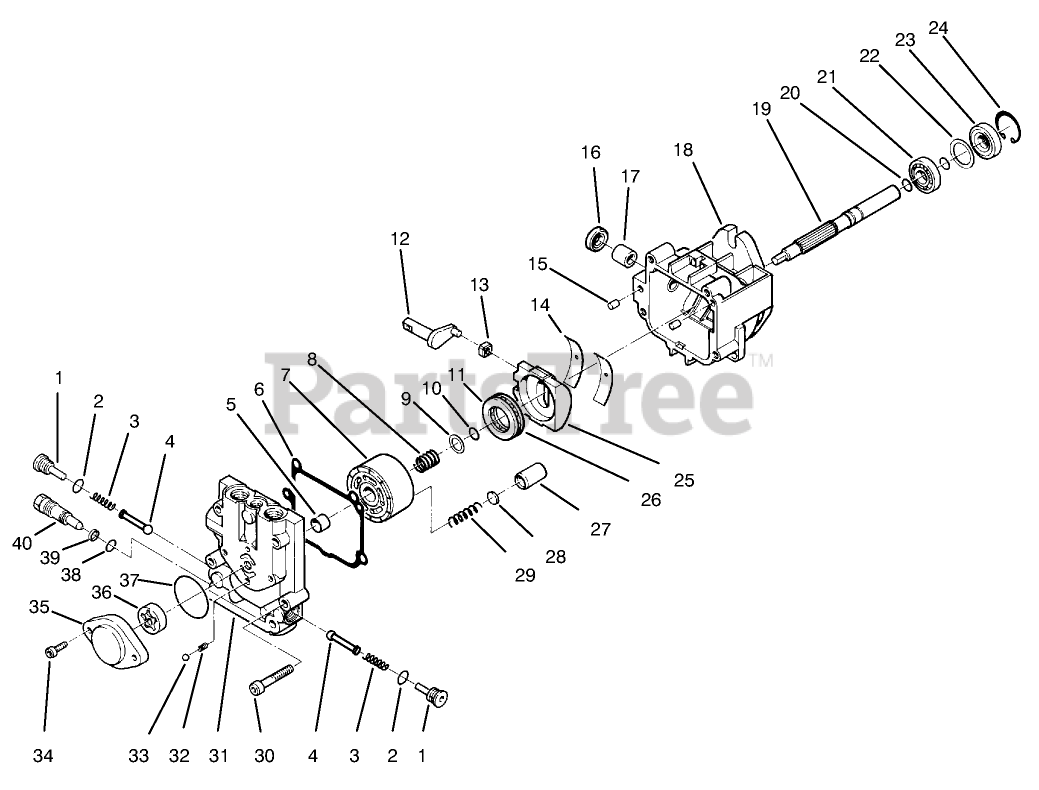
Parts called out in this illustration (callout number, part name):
1	Check Valve Kit (Incl. Ref. #2-4)
2	Seal-O-Ring
4	Poppet
5	Journal-Bearing
6	Gasket-End Cap
9	Washer
11	Plate-Thrust
12	Arm-Trunnion
13	Guide-Slot
14	Cradle-Bearing
16	Seal-Lip
17	Journal-Bearing
19	Shaft
21	Bearing-Ball
23	Seal-Lip
25	Swashplate Assembly
26	Roller-Thrust
29	Spring-Piston
32	Ball
35	Housing-Charge Pump
36	Gerotor Assembly
37	Seal-O-Ring
38	Seal-O-Ring
39	Ring-Back-Up
40	Valve-Bypass
